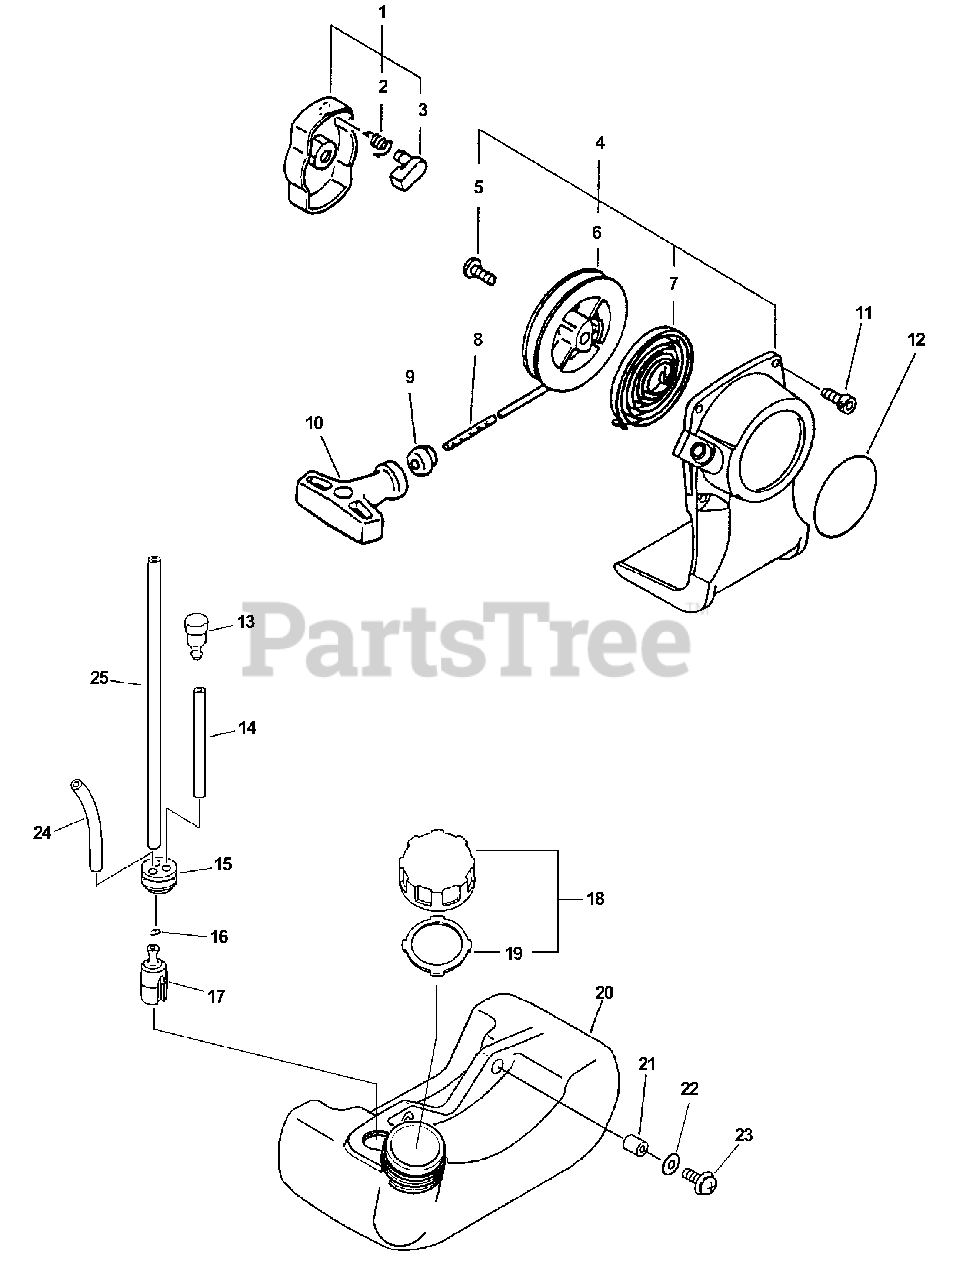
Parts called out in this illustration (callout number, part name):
1	STARTER PAWL ASSY
2	SPRING, RETURN
3	PAWL, STARTER - BLACK
4	STARTER ASSY
6	REEL, ROPE
7	SPRING, REWIND
8	ROPE, STARTER - 3X890
9	GUIDE, ROPE
10	GRIP, STARTER
11	SCREW - 4X16
12	LABEL - ECHO
13	VENT, FUEL TANK
14	PIPE - 3X5X70 -- BLACK
15	GROMMET
16	CLIP - 6
17	FILTER, FUEL
18	CAP ASSY
19	GASKET, CAP
20	TANK, FUEL
22	WASHER - 5
23	SCREW - 5X16
24	PIPE - 3X6X90 -- CLEAR
25	PIPE - 3X5X180 -- BLACK
